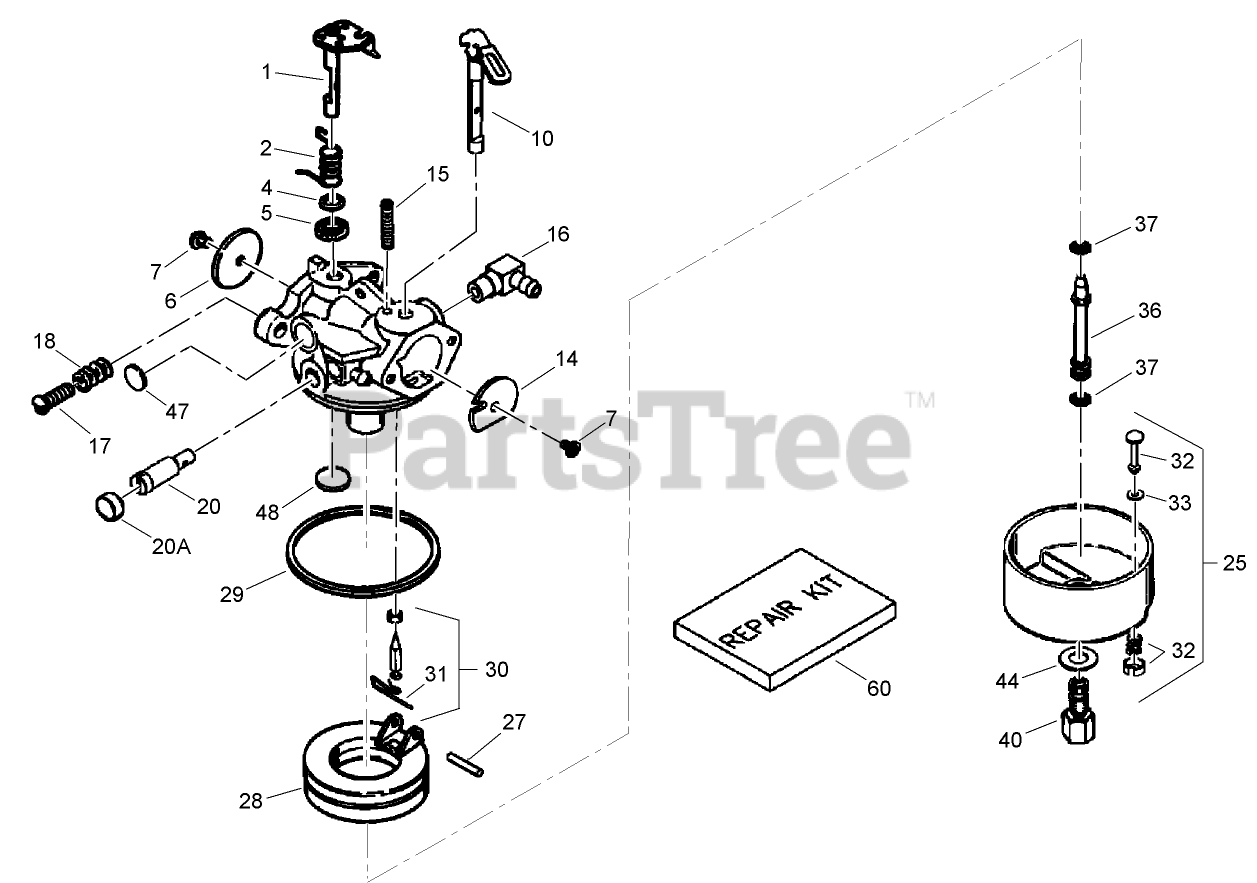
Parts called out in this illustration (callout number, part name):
1	Throttle Shaft and Lever ASM
2	Spring-Return, Throttle
4	Washer-Seal, Dust
5	Seal-Dust
6	Shutter-Throttle
7	Screw-Shutter
10	Choke Shaft and Lever ASM
14	Shutter-Choke
15	Spring-Positioning, Choke
16	Fitting-Fuel
17	Screw-Throttle Crack and Idle Speed
18	Spring-Tension
20	Screw-Restrictor, Idle
20A	Cap-Screw, Idle Restrictor
25	Float Bowl Asm. (Incl. Ref. # 32, 33)
25	Bowl-Float (no drain)
27	Shaft-Float
28	Float (Plastic)
29	O Ring-Bowl, Float
30	Inlet Needle, Seat Clip Assy. (Incl. No. 13)
31	Clip-Spring
32	Bowl Drain ASM
33	Gasket-Plunger, Drain
36	Tube-Nozzle, Main
37	O-Ring
40	Nut-Bowl, High Speed
44	Washer-Nut, Bowl
47	Plug-Welch, Idle Mixture Well
48	Plug-Welch, Atmospheric Vent
60	Repair Kit
